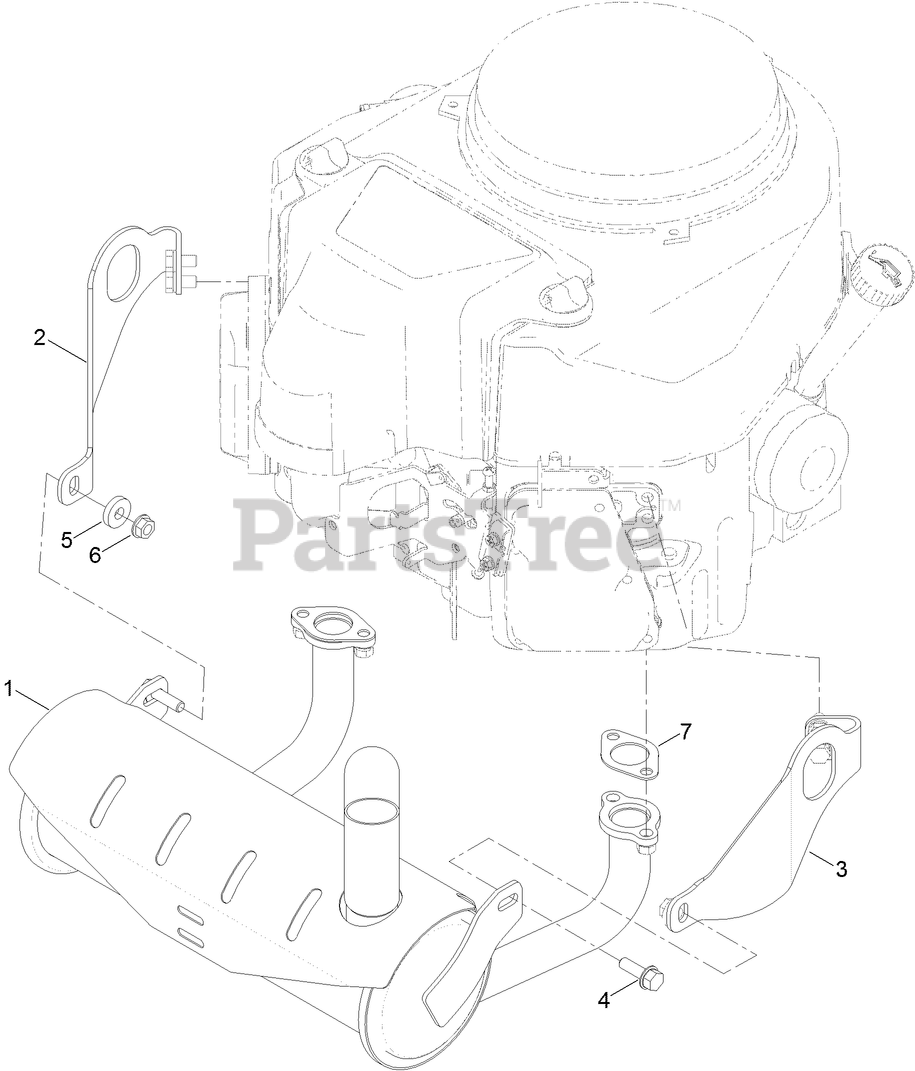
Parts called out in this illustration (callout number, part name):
1	MUFFLER
2	BRACKET-MUFFLER, RH
3	BRACKET-MUFFLER, LH
4	SCREW-HHF
5	SPACER
6	NUT-HF
7	GASKET-EXHAUST
